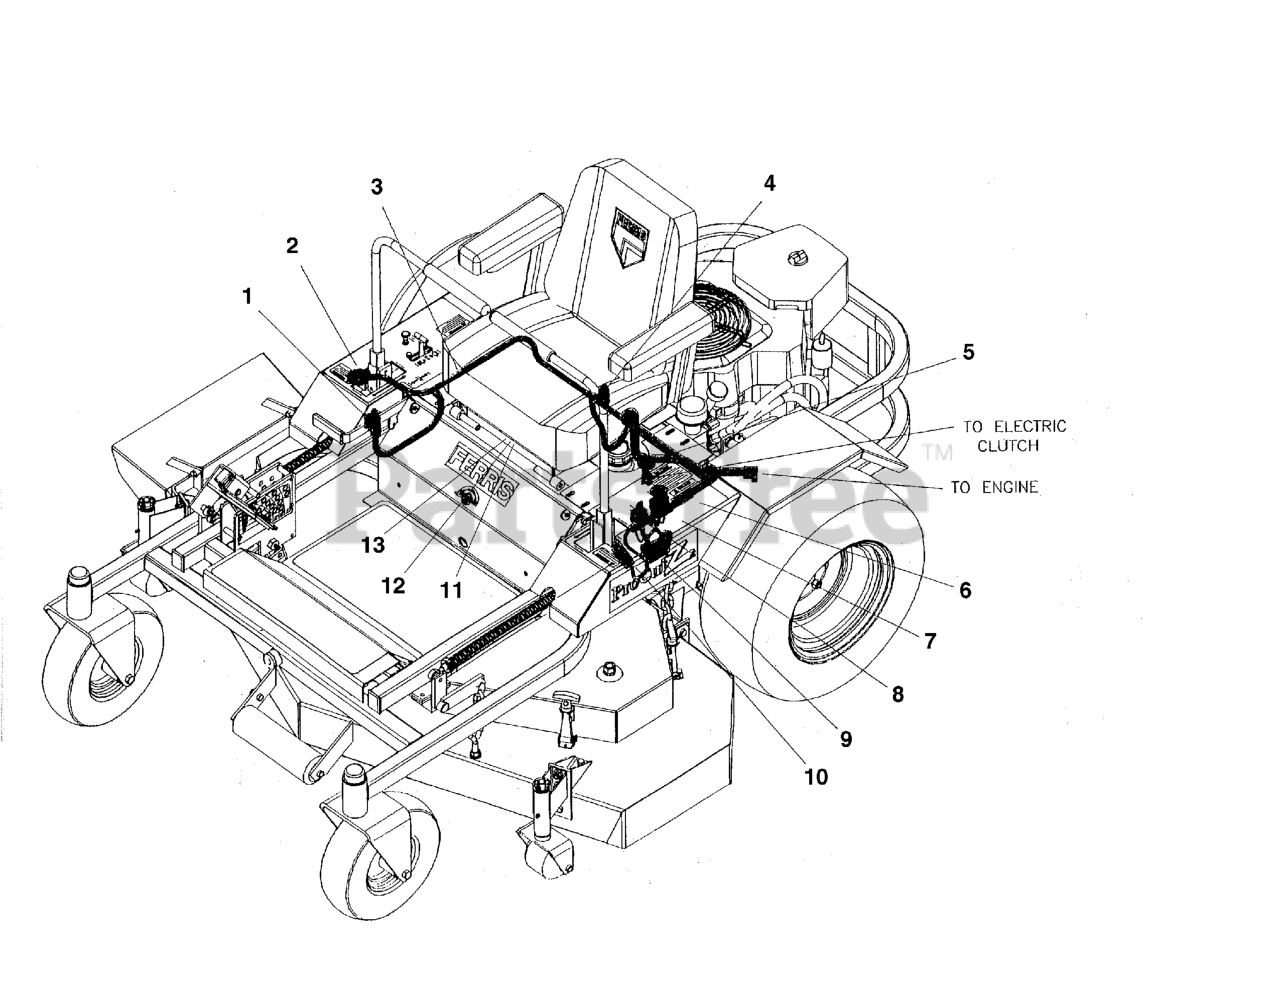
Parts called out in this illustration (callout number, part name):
1	SWITCH, Plunger, NO/NC
2	SWITCH, Plunger, NO
3	HARNESS, Wire PCZ
4	SWITCH, DP NO/NC SNAP-IN
5	GROMMET, 7/8"
6	HOUR METER
7	SWITCH, BLADE ENGAGEMENT
8	SWITCH, IGNITION, 6 POST
9	FUSE BLOCK
10	SWITCH, PLUNGER, N.O./N.C.
11	CABLE, Positive (+) Battery
12	BATTERY CABLE, NEG, 22, 1/4-5/16
13	CABLE, Ground
